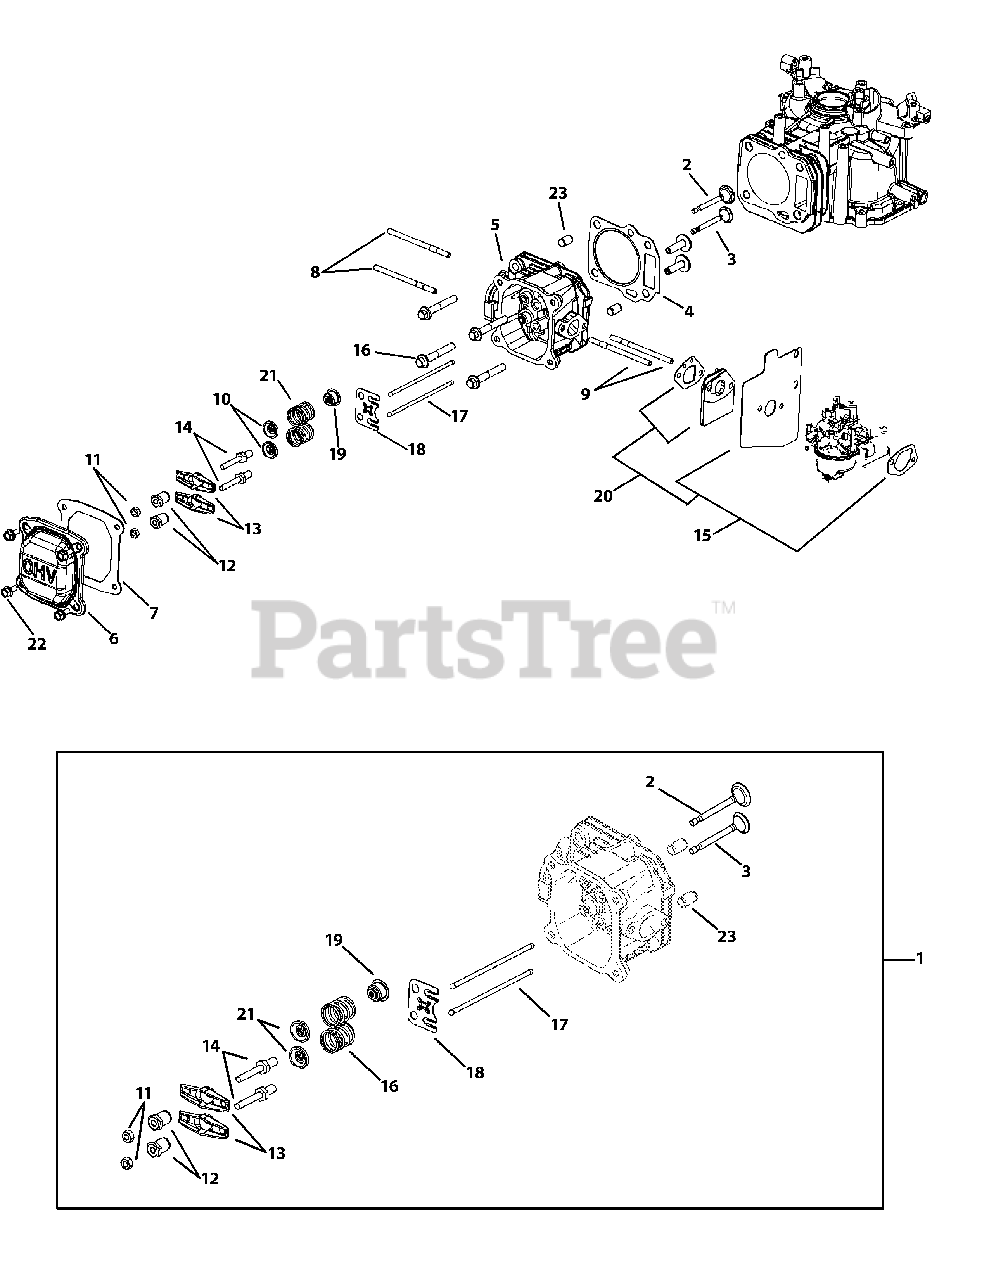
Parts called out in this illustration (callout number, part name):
1	Valve Train Kit
3	Exhaust Valve
4	Head Gasket Kit (Inc. Muffler Gasket)
5	Cylinder Head Kit
7	Valve Cover Gasket
8	Stud Kit, M6
9	Carburetor Stud
10	Valve Spring Retainer
12	Rocker Arm Pivot
14	Rocker Arm Stud
15	Gasket Kit
16	Hex Flange Screw, M8
18	Pushrod Guide Plate
19	Valve Stem Seal
22	Hex Flange Screw, M6
23	Cylinder Head Dowel
